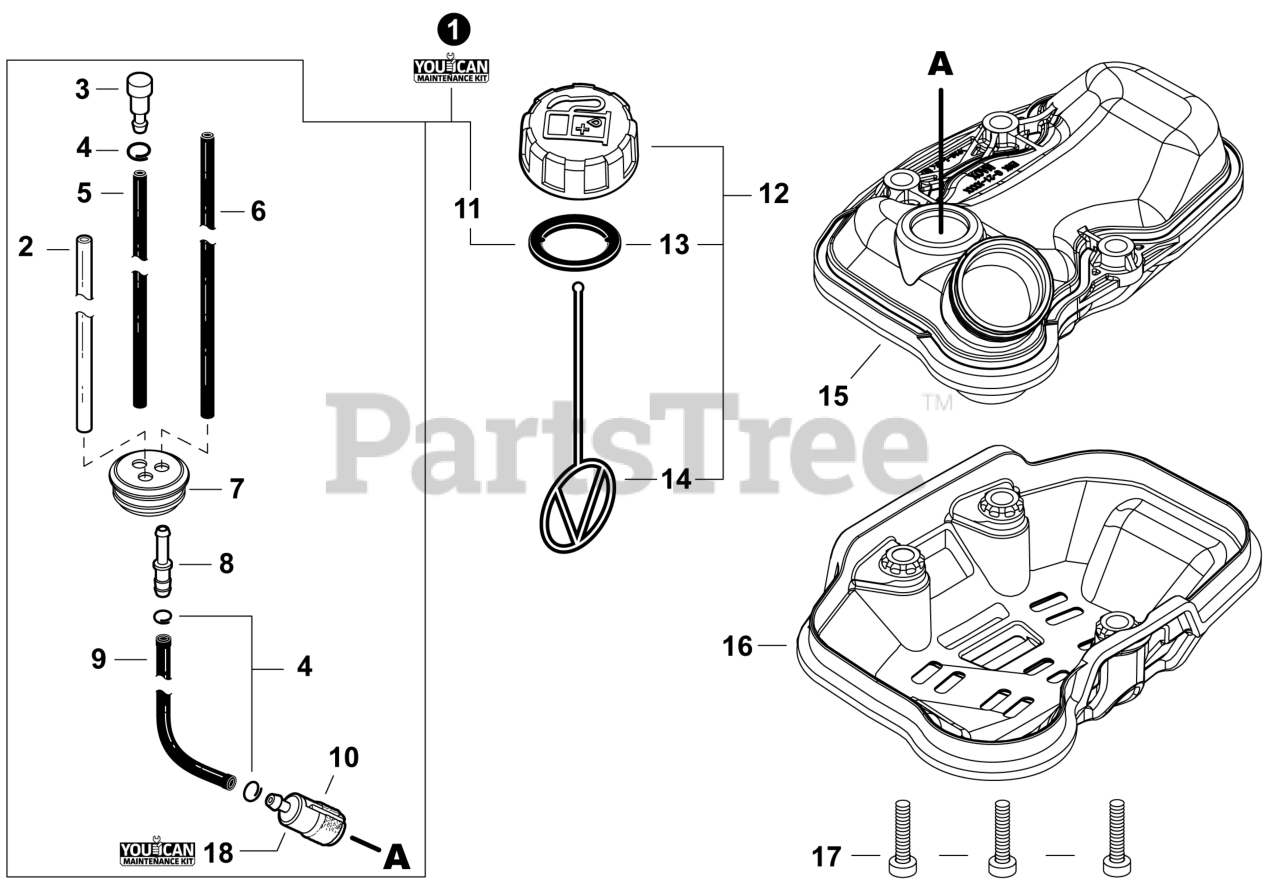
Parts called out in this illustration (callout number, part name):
1	FUEL SYSTEM KIT - YOUCAN™
2	PIPE, FUEL 3x6x85 YELLOW
3	VENT ASSY
4	CLIP 6
5	PIPE, FUEL 3x5x90 BLACK
6	PIPE, FUEL 3x5.5x78 BLACK
7	GROMMET, FUEL
8	CONNECTOR, PIPE 5x3.5
9	PIPE, FUEL 3x5x105 BLACK
10	FILTER, FUEL
11	GASKET, FUEL CAP
12	CAP ASSY, FUEL
13	GASKET, FUEL CAP
14	CONNECTOR, CAP L= 123
15	TANK, FUEL
16	GUARD, FUEL TANK
17	BOLT, TORX 5x25
18	TUNE-UP KIT - YOUCAN™
